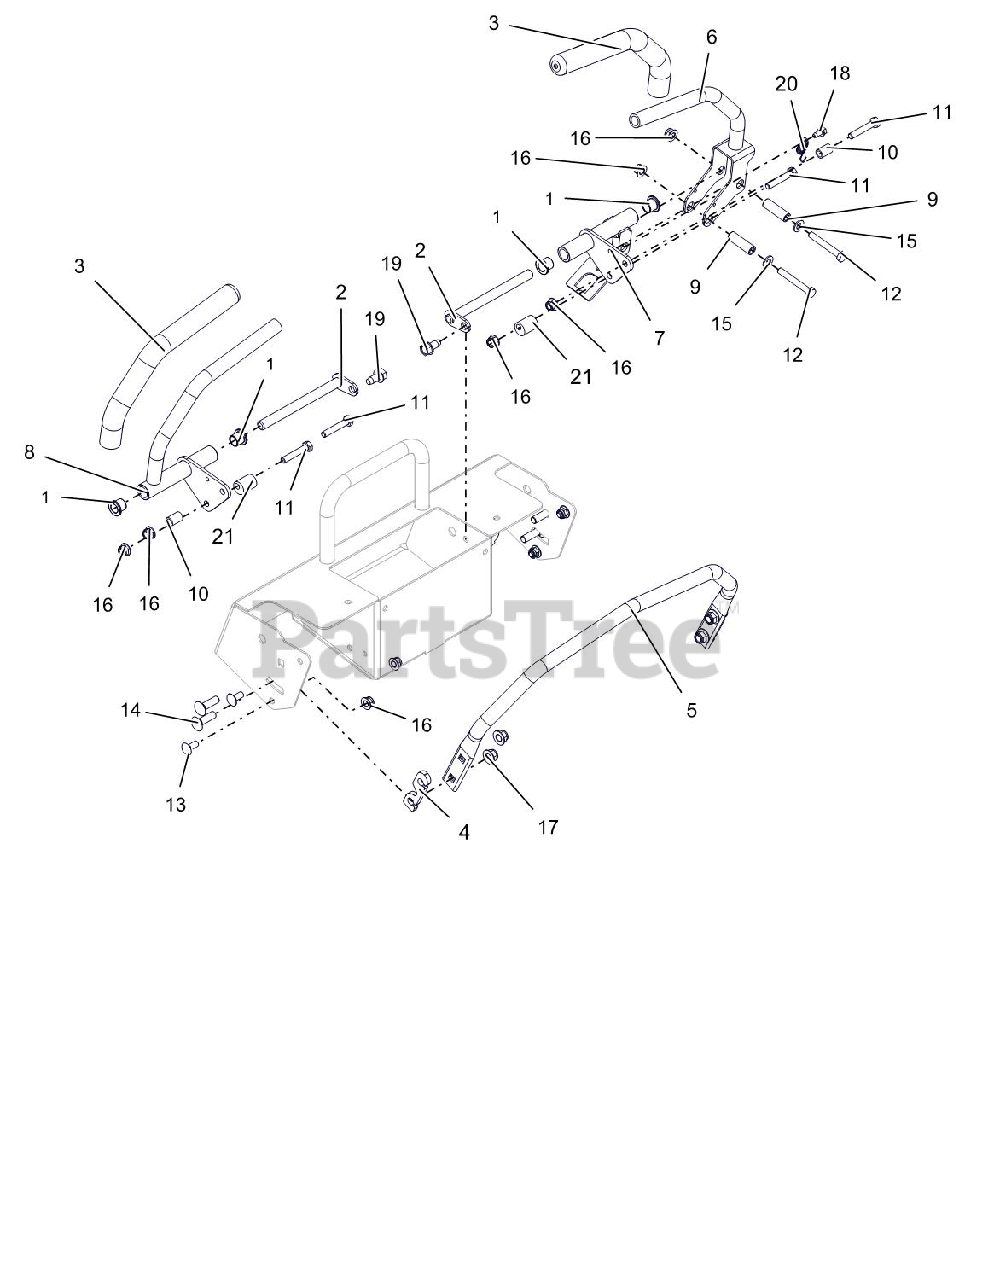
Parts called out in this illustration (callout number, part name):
1	BRG, FLG .500X.620X.500 BRNZ
2	WLDT, PIN AND LOCK Y
3	GRIP, HANDLEBAR
4	SHIM, 5 DEG SPEED BAR
5	BAR, FORWARD STOP PRO-STANCE
6	WMT, CONTROL ARM OPC
7	WMT, CONTROL ARM (LH)
8	WMT, CONTROL ARM (RH)
9	BSHG-SLV .325X.49X1.56
10	BSHG-SLV .328X.50X.75
11	@BLT-HEX .31-18X1.75 GR5 YWZC
12	@BLT-HEX .31-18X2.25 GR5 YWZC
13	@BLT-RDHDSQNK .31-18X.75 G5YZ
14	@BLT-RDHDSQNK .38-16X1.25 G5YZ
15	@WSHR-FL-STL.344X.688X.065YWZC
16	@NUT-LK-NYL-FLG .31-18 YWZC
17	@NUT-LK-NYL-FLG .38-16 YWZC
18	SCR-TAP .25-20X.50 HWH TR YWZ
19	@SCR-TAP .38-16X.75 HWH TR YWZ
20	SPRING, EXT. .043X.438X1.64
21	ECCENTRIC
